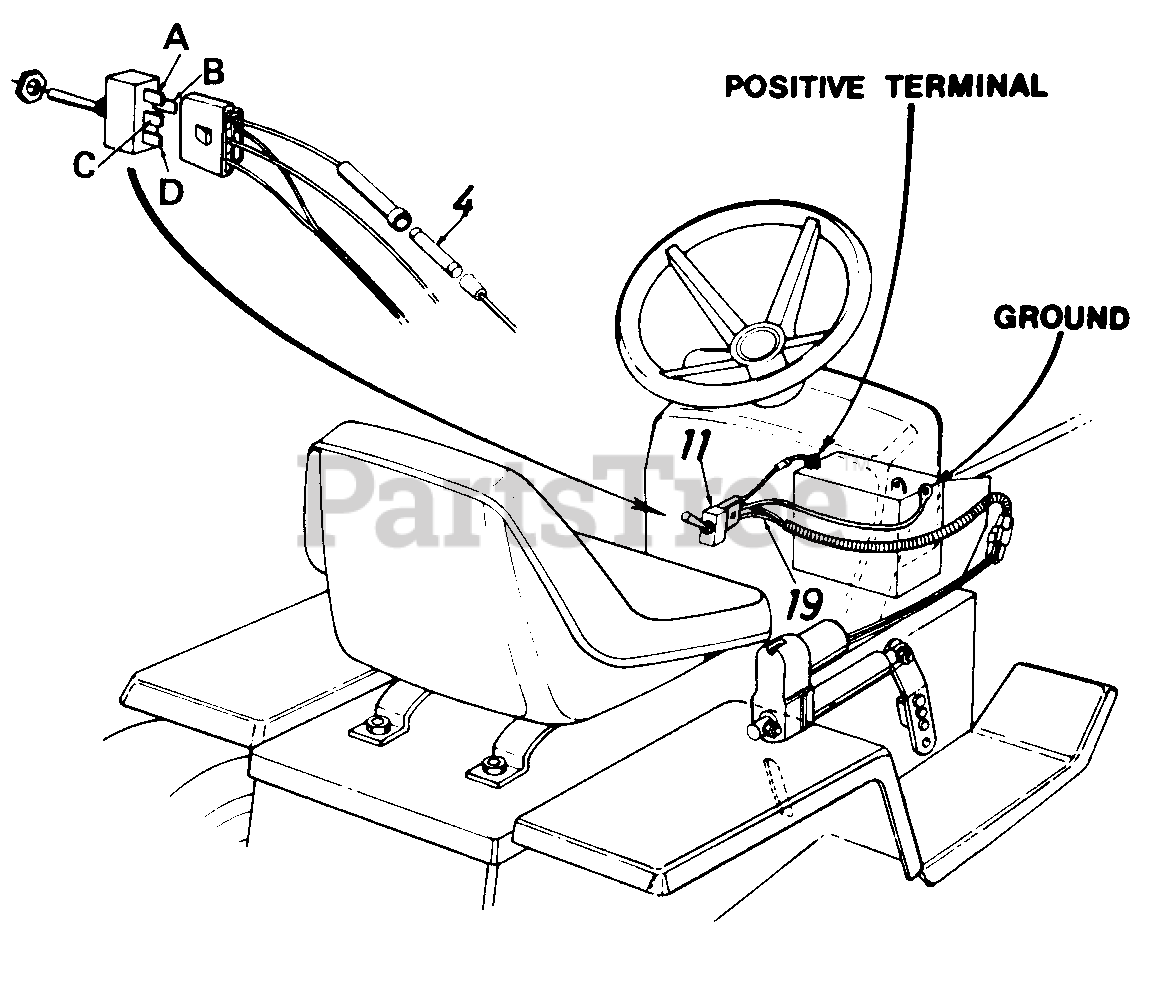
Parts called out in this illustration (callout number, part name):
4	Shaft, Input
11	Ring, Snap
19	Wire Harness
A	Connects to Positive Terminal on Battery
B	Connects to Actuator
C	Ground Wire-to Frame
D	Connects to Actuator
